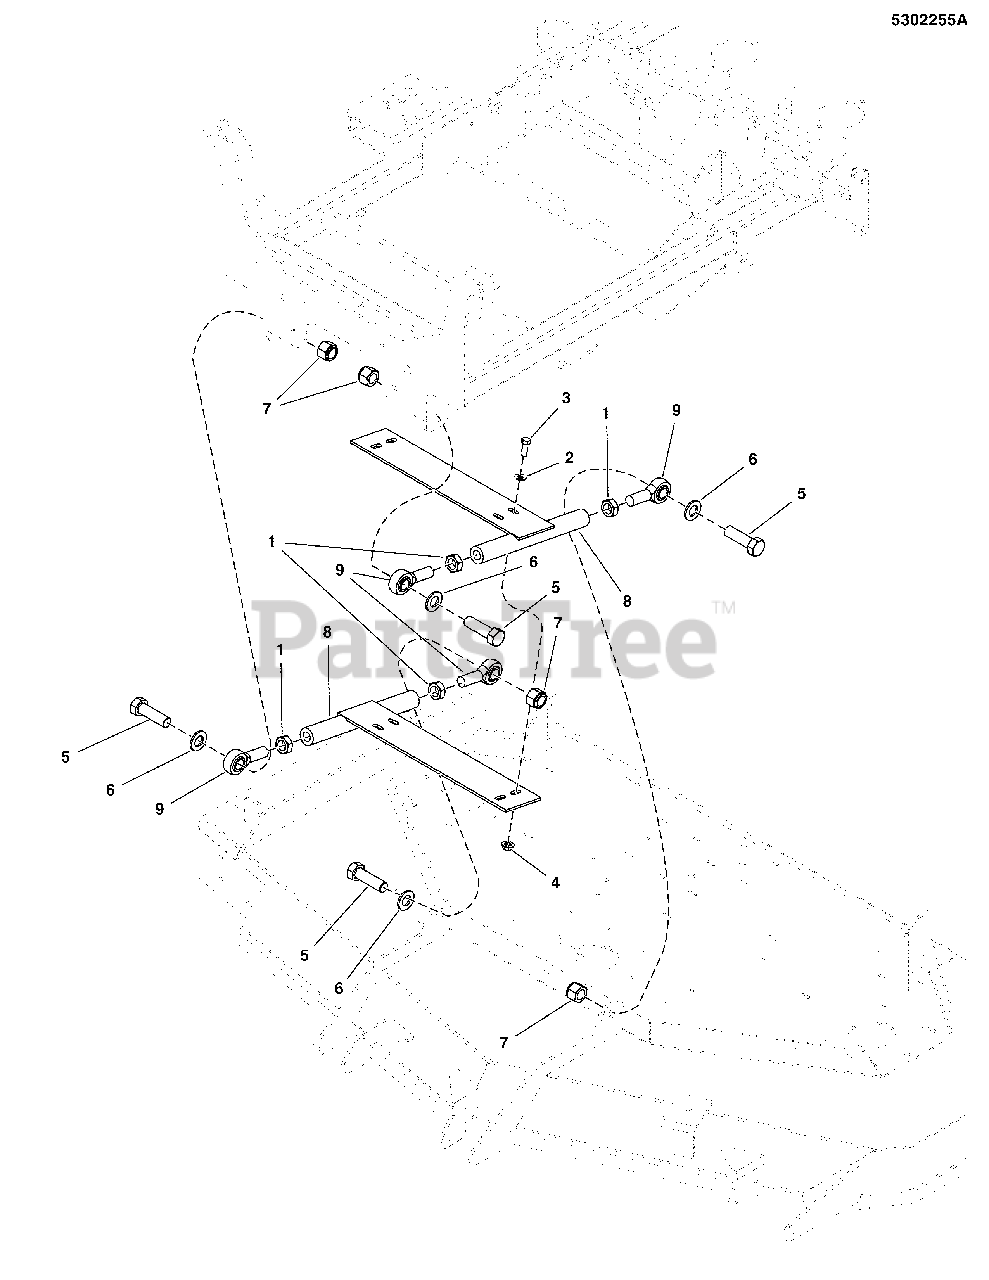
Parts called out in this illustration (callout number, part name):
1	NUT, 3/4-16 HEX JAM
2	WASHER, 3/8 SAE
3	BOLT, 3/8-16 X 1 GD5 YZ
4	NUT, 3/8-16 HEX SERRATED FLANGE
5	BOLT, 3/4-16 X 2-1/2 YZ GD8
6	WASHER, 3/4 SAE
7	NUT, 3/4-16 HEX NYLON LOCK
8	WELD, DECK STABILIZER, IS2500Z-246 - BLK
9	BALL JOINT, 3/4-16, MALE
